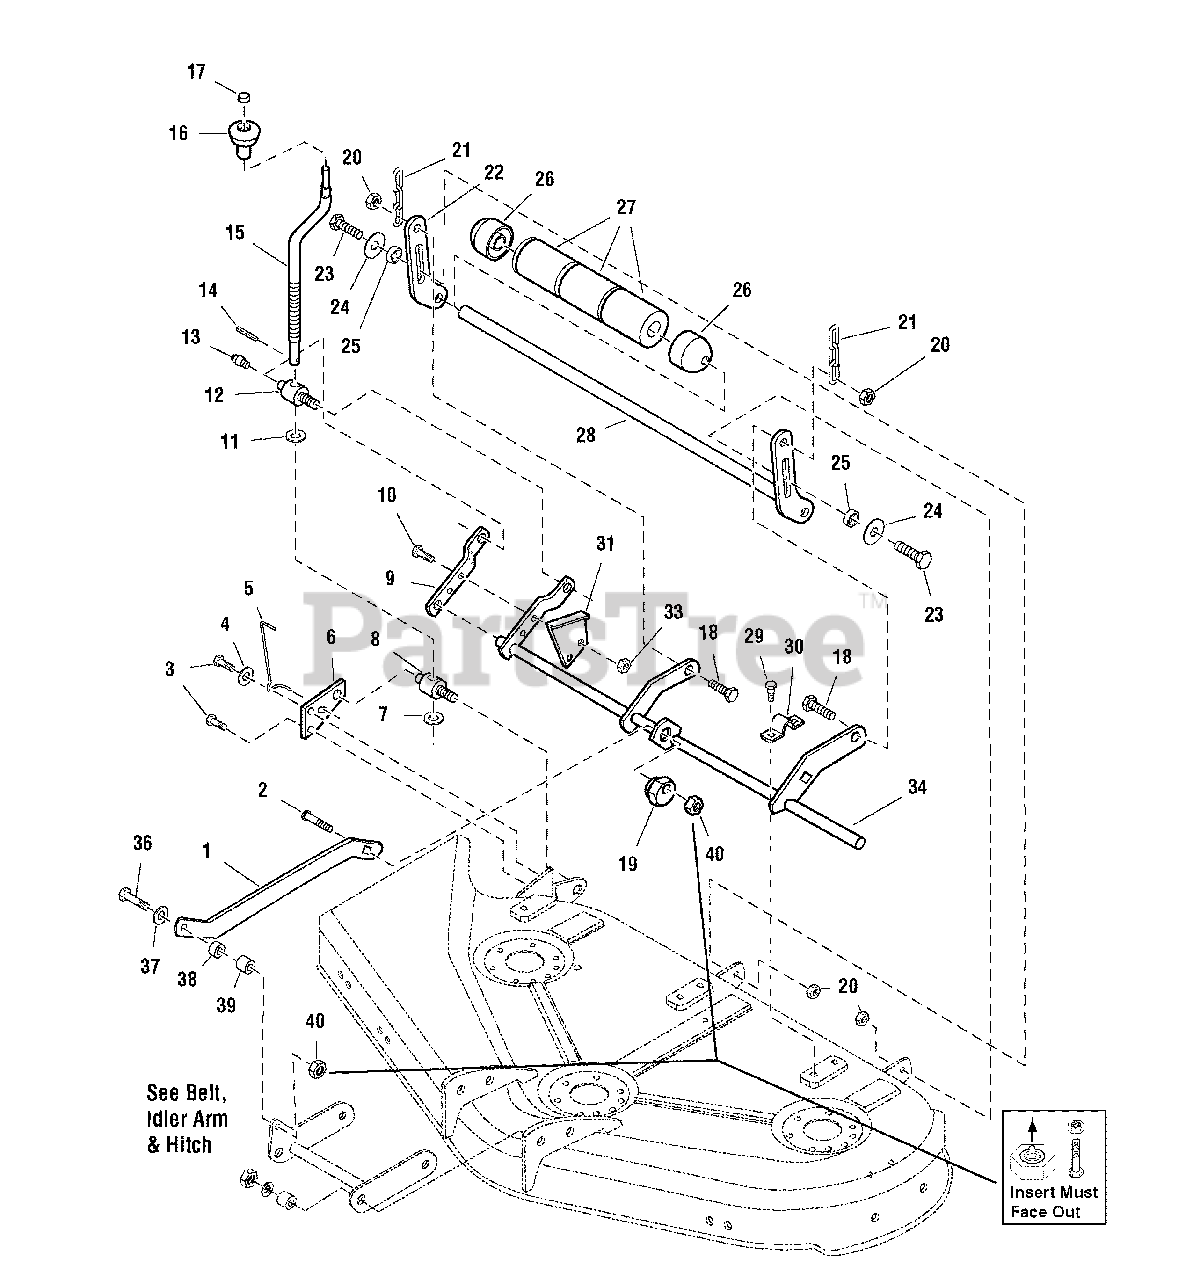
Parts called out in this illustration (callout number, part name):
2	CARRIAGE BOLT,3/8-16 x 1-1/2, Black
3	CAPSCREW, Hex Washer Head, Tap Tite, 5/16-18 x 1-1/4, Black
4	WASHER, 5/16, Black
5	ROD, Height of Cut
7	WASHER, Detent, Black
10	CAPSCREW, Hex Head, 5/16-18 x 1-1/4, Black
11	WASHER, 1/2, Black
13	FITTING, Lube
14	PIN, Spring
15	CRANK, Height Adjustment, Black
16	KNOB, Spinner
17	NUT, Push, 3/8, Black
18	CAPSCREW, Hex Head, 3/8-16 x 1-1/2, Black
19	NUT, Hex Adjusting, .99 DIA .687
20	NUT, Hex Flange Lock, 3/8-16, Black
21	CHAIN, Link, 3 Links
22	BAR, Roller
23	CAPSCREW, Hex Head, 5/16-18 x 1-1/4, Black
24	WASHER, 5/16, Black
26	ROLLER, Rounded, 5/8 ID x 2-1/2 OD x 2" Long
27	ROLLER, 5/8 ID x 2-1/2 OD x 4" Long
28	SHAFT & BAR ASSEMBLY
29	CAPSCREW, Hex Washer Head, Tap Tite, 5/16-18 x 3/4, Black
30	STRAP
31	BRACKET, Height of Cut
33	NUT, Hex, 5/16-18, Whiz Lock Flange
34	SHAFT ASSEMBLY
36	CAPSCREW, Hex Head, 3/8-16 x 1-3/4
37	WASHER
40	NUT, Hex, 3/8-16
